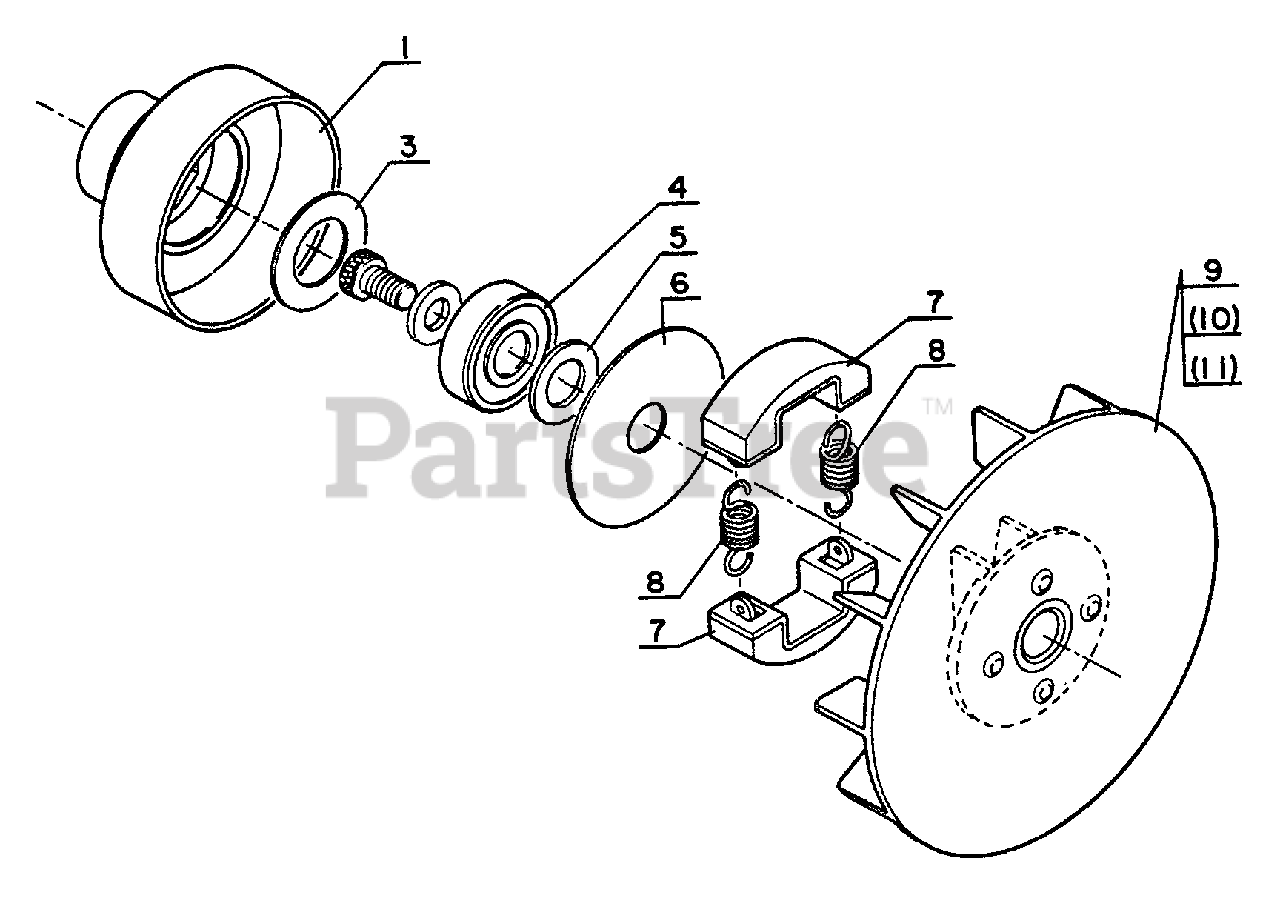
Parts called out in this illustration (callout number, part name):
1	DRUM, CLUTCH
3	WASHER, CLUTCH
4	BEARING, BALL - 6000
5	WASHER, CLUTCH
6	PLATE, CLUTCH
7	SHOE, CLUTCH
8	SPRING, CLUTCH
9	FAN
